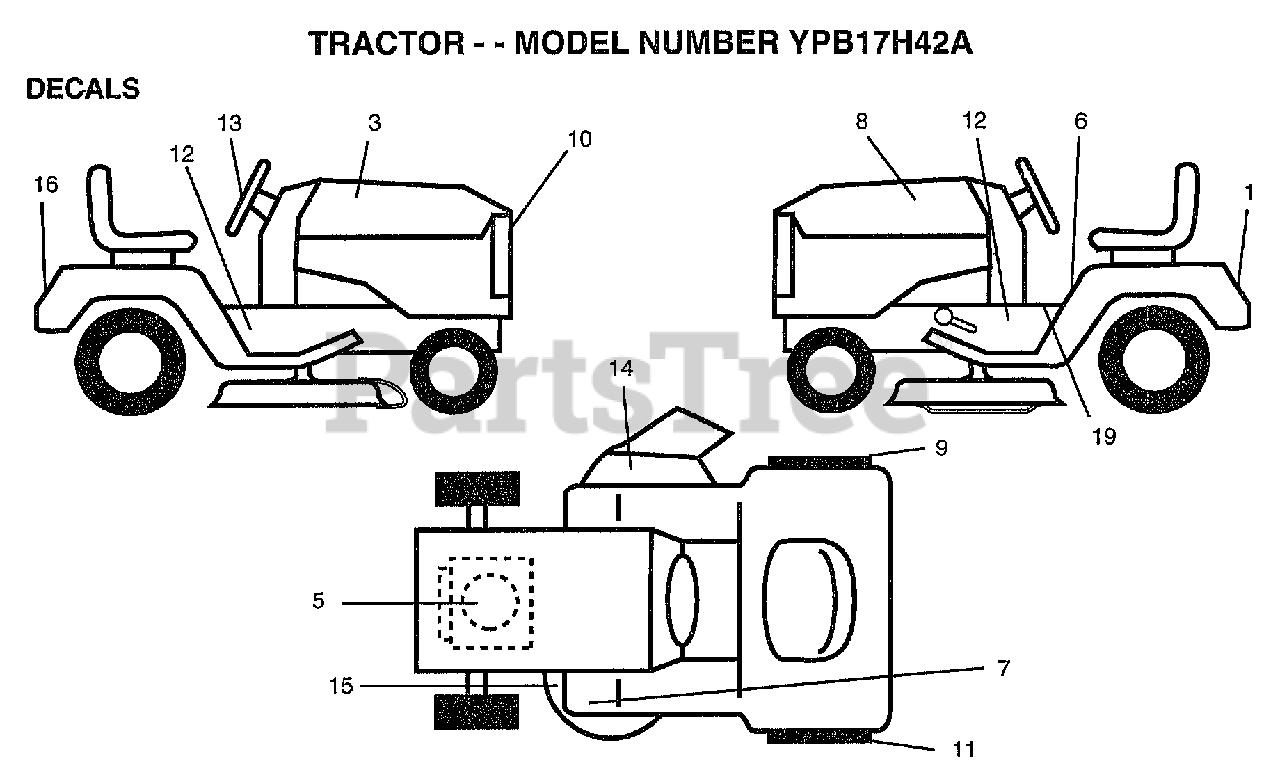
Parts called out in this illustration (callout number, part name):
1	DECAL DRAWBAR LH
3	DECAL
5	DECAL.ENGINE.HP.B&S
6	DECAL.CAUT.ENG/FR
7	DECAL T
8	DECAL
9	DECAL FENDER RH
11	DECAL FENDER LH
12	DECAL CHASSIS
13	DECAL INS STRG WH
14	"DECAL, WARNING"
15	"DECAL-SCHEM,BELT"
16	DECAL FENDER
19	DECAL SADDLE OPER
